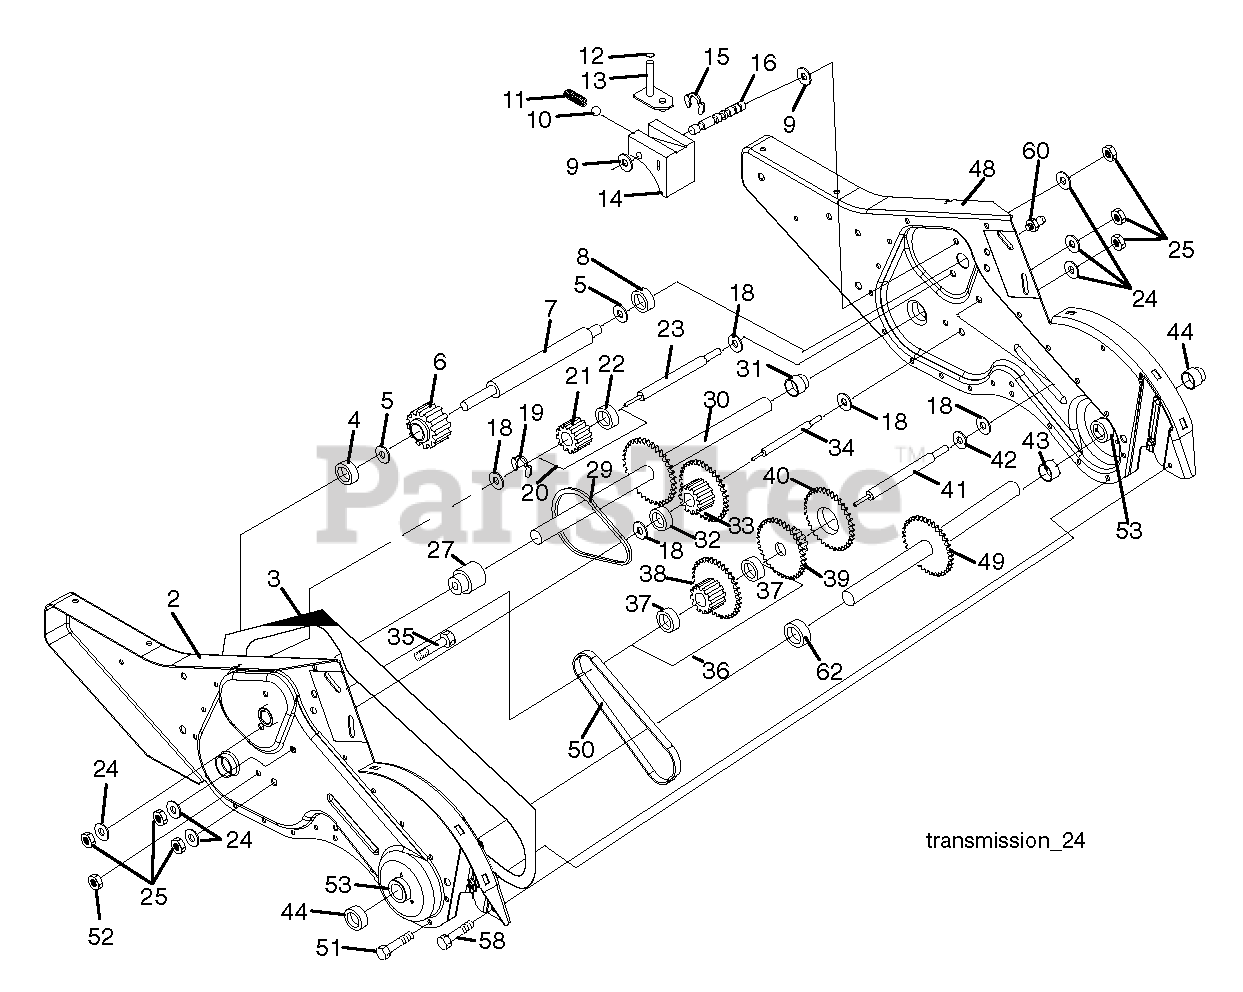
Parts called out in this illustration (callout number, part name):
2	GEARCASE.ASM.CRT.LH.W
3	GASKET.GEARCASE.CRT/DRT.
4	NEEDLE BRNG LT
5	THRUST WASHER
6	Pinion Input Gear, CRT Tiller
7	SHAFT.INPUT."D"".TILLER
8	Needle Bearing, .875 X .687 Oe.50
9	WASHER, SEAL
10	BALL, STEEL
11	SPRING-SHIFT CRT
12	O-RING TI
13	SHIFTING ARM
14	SHIFT FORK TI
15	KLIP RING
16	SHAFT.SHIFTER.TILLER
19	KLIP RING
20	GEAR ASSY CRT
21	GEAR-REV IDLR CRT
22	NEEDLE BEARING TI
23	SHAFT CRT
24	LOCKWASHER
25	NUT.ASF.HEX.7/16
27	BEARING.GROUND.DRIVE
29	CHAIN CRT
30	GROUND SHAFT ASS'Y
31	BEARING, SHAFT RH CRT
32	SPACER TI
33	SPRCKT 8 GEAR CRT
34	SHAFT.SECONDARY.REDUCTION.CRT
35	SCRW WHIZ LOK CRT
36	SPROCKET.ASM.W/BEARING.TILLER
37	Needle Bearing, .875 X .687 Oe.50
39	GEAR TI
41	SHAFT.REDUCTION.TILLER
42	BRNG RACE T
43	SPACER TI
44	SEAL ASM, OIL
48	GEARCASE.ASM.CRT.RH.W/BEARING
49	SHAFT.ASM.TINE
50	CHAIN.TILLER
51	SCREW
53	BEARING KIT
58	BOLT SHOULDER 1/4-20 UNC X.875
60	FITTING.GREASE.TAPERED
62	SPACER.1.015X1.50X.650
